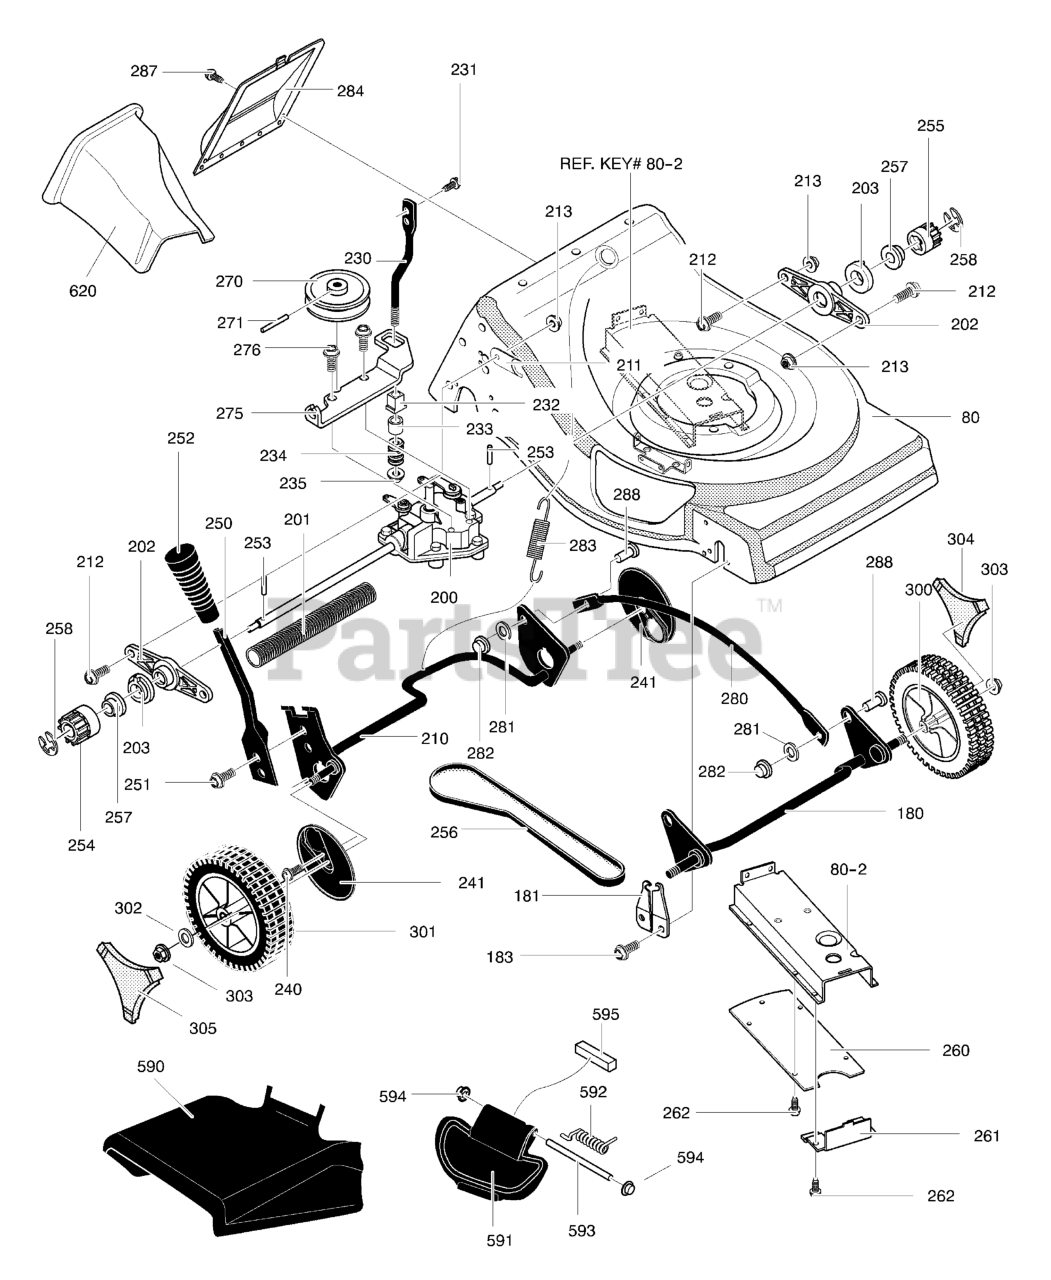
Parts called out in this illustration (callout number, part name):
80	Assy., Frame
180	Assy., Crossbar Front
181	Bushing, Front
183	Screw, 1/4-14x.50
200	Transmission *
201	Shield, Axle
202	Support, Axle
203	Bearing, Lifter
210	Assy., Crossbar RR
211	Retainer, Bearing
212	Screw, 5/16-18 x 0.75
213	Nut, 5/16-18
230	Support, Spring
231	Screw, 1/4-20x.63
232	Bushing, Spring
234	Spring, Compression
235	Nut, 5/16-18
240	Screw, 1/4-14x.50
241	Dust Cover
250	Lever, Spring
251	Screw, 1/4-20x.63
252	Knob, Hgt Adjust
253	Pin, Drive
254	Gear, Pinion Right
255	Gear, Pinion Left
256	Belt, 2L 15.75L
257	Flatwasher
258	Ring, Ret. E
260	Cover, Lower Belt Guard
261	Cover, Front Belt
262	Screw, 10-16x.50
270	Pulley, 2L
271	Pin, Spring
275	Bracket, Transaxle
276	Screw, 1/4-20x.50
280	Link, Lifter
281	Nut, Push On
282	Cap, Push On
283	Spring, Ext.
284	Cover, Rear Trans.
287	Screw, 1/4-20x.63
288	Pin, Clevis
300	Tire & Rim
301	Wheel, Drive
302	Washer, Flat
303	Nut, 3/8-16
304	Cap, Front Hub
305	Cap, Rear Hub
590	Chute, Side Discharge
591	Cover, Mulch
592	Spring, Torsion
593	Rod, Pivot
594	Cap, Push On
595	Pad, Foam
620	Plug, Mulch
